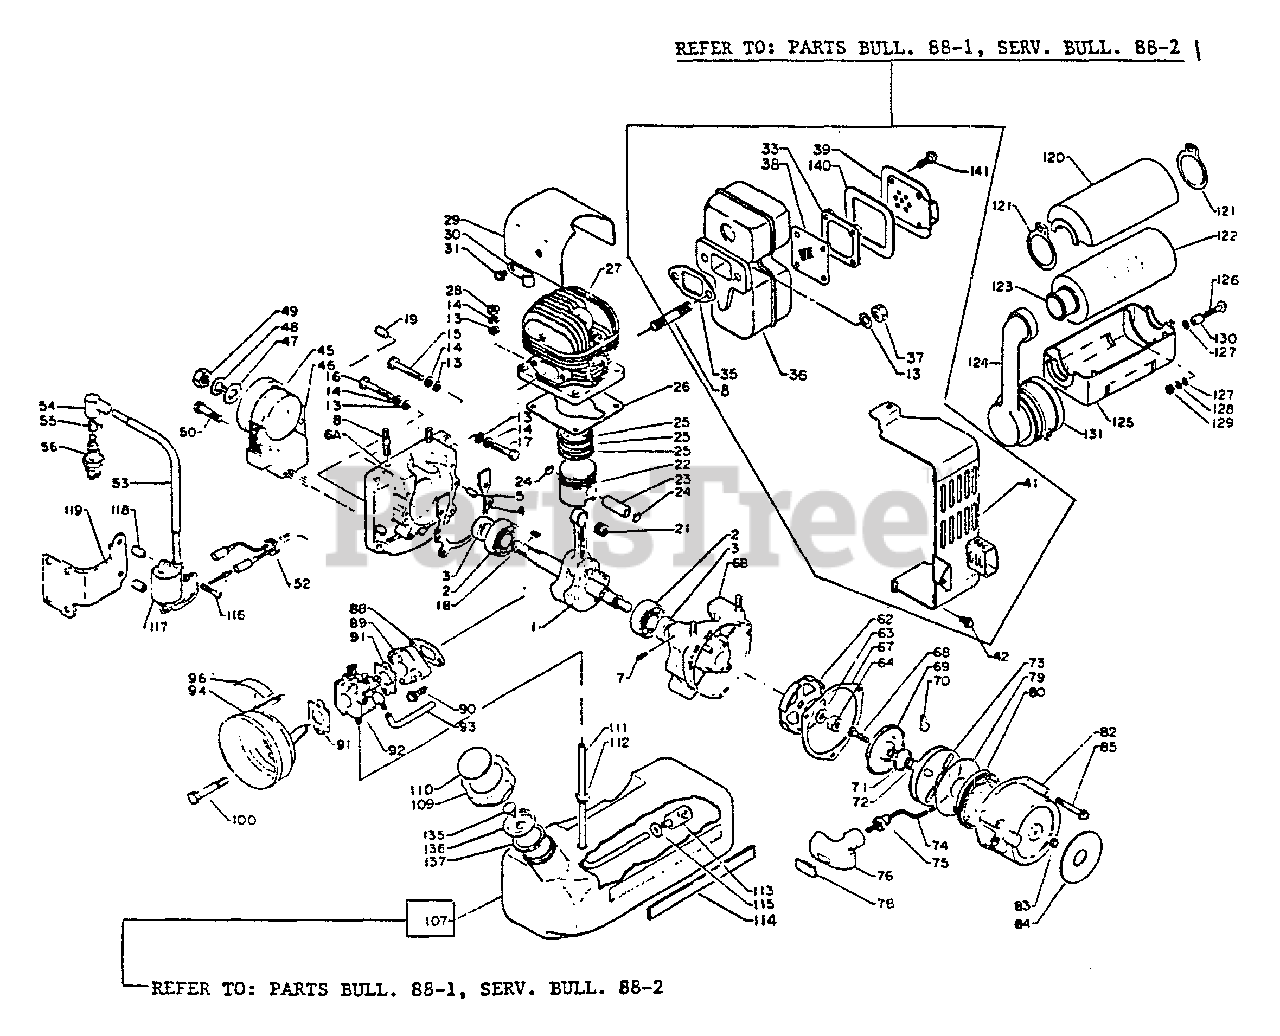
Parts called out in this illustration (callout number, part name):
1	CRANKSHAFT ASSY
2	BEARING, BALL 6202
3	SEAL, OIL
4	GASKET, CRANKCASE
5	PIN, LOCATING 5×10
6	CRANKCASE KIT
6A	CRANKCASE KIT
7	CONNECTOR
13	WASHER 6.5×11.5×0.8
14	WASHER, SPRING 6
17	BOLT 6×25
21	BEARING, NEEDLE
22	PISTON
23	PIN, PISTON
24	RING, SNAP 8
25	RING, PISTON
26	GASKET, CYLINDER
27	CYLINDER
28	NUT, HEX M6
29	COVER, CYLINDER
30	CLIP, CORD
31	BOLT 6×10
33	SEAT, SCREEN
35	GASKET, EXHAUST
37	NUT, LOCK 6
38	SCREEN KIT
39	GUIDE, EXHAUST
41	COVER, MUFFLER
42	SCREW 5×12
45	FLYWHEEL
46	COIL, IGNITION
48	WASHER, SPRING
50	SCREW 5×25
53	TUBE, INSULATOR
54	CAP, SPARK PLUG
55	TERMINAL, SPARK PLUG CAP
56	SPARK PLUG - BM6A
62	PAWL CATCHER
63	WASHER, CLUTCH
67	GASKET, STARTER
69	PLATE, FRICTION
70	RATCHET
71	SPRING
72	SPRING
73	REEL, ROPE
74	ROPE, STARTER 4.0×880
75	GUIDE, ROPE
76	GRIP, STARTER
78	COVER, HANDLE
79	PLATE, STARTER
80	SPRING, RECOIL
82	CASE, STARTER
83	NUT - 5 -- CAP
84	LABEL, ECHO
85	SCREW 5×42
88	GASKET, INTAKE
89	INSULATOR
90	SCREW 6×25
91	GASKET, INTAKE
92	CARBURETOR - WA-55
93	PIPE
94	CASE, AIR FILTER
96	LABEL - CHOKE
100	BOLT
107	TANK, FUEL
110	LABEL - FUEL MIX
111	PIPE, FUEL W/GROMMET 3×5×250L
113	FILTER, FUEL
114	LABEL - NAME
115	WASHER 5.5×12×0.8
116	SCREW 4×25
117	COIL, IGNITION
120	COVER, AIR FILTER
122	FILTER, AIR
123	HOLDER, AIR FILTER
124	ADAPTER, INTAKE
125	CASE, AIR FILTER
126	BOLT
127	WASHER, FLAT 5.5×10×0.8
128	WASHER, SPRING 5
129	NUT M5
131	CLAMP
135	VALVE, CHECK
136	HOLDER, VENT
137	GASKET
140	GASKET
141	SCREW 4×14
